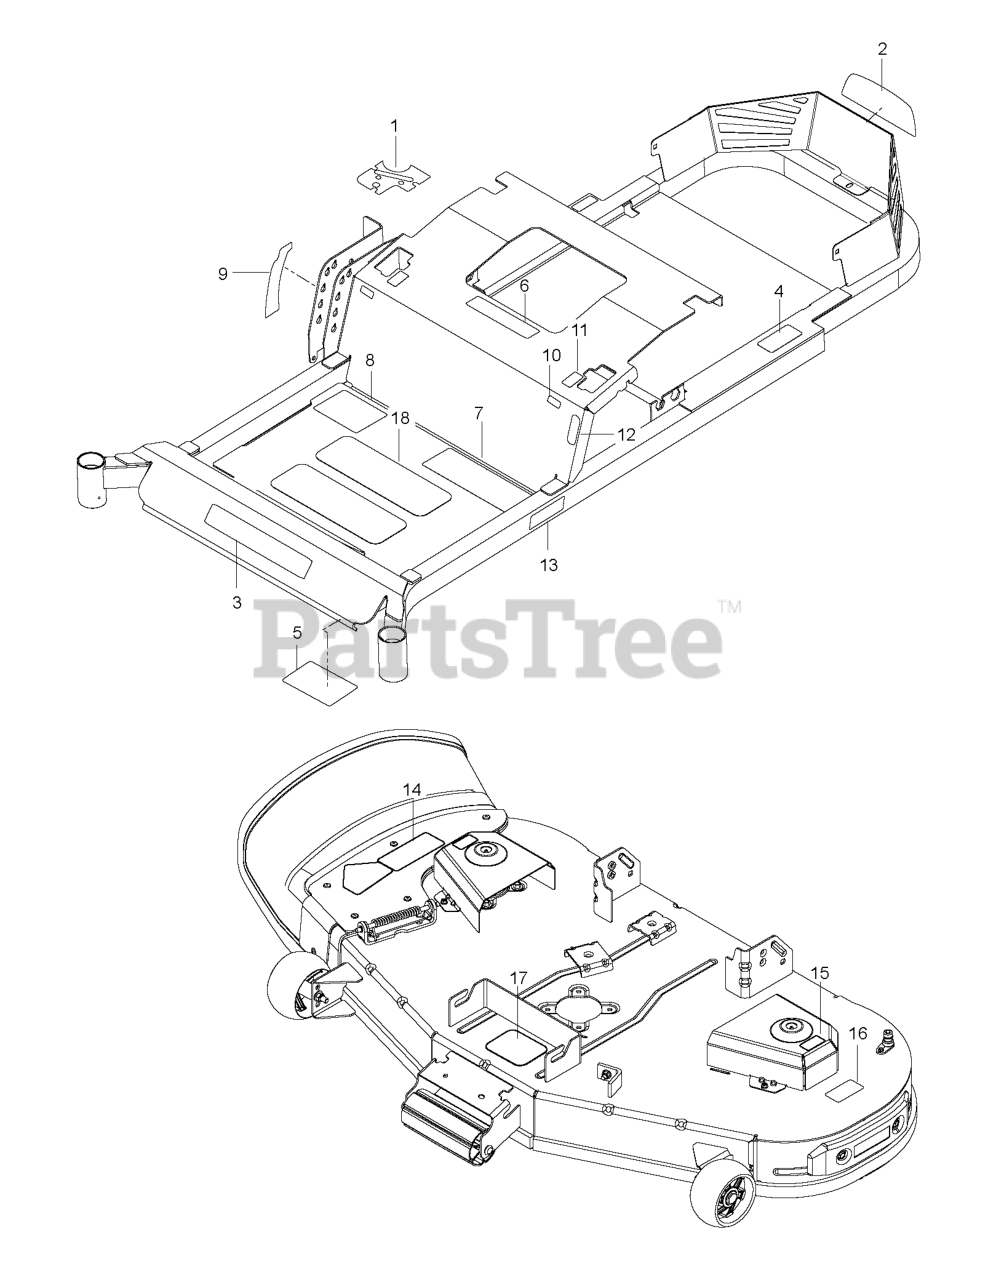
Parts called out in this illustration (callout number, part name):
1	DECAL CTRL PANEL GRAPHIC DECAL
2	DECAL ZTR BRAND GRAPHIC DECAL.
3	DECAL ZTR BRAND GRAPHIC DECAL.
4	DECAL, DO NOT TOW
5	DECAL, SERVICE
6	EURO DECAL-BATTERY WARNIN6
7	DECAL ZTR WARNING DECAL DECAL.
8	DECAL ZTR STARTING DECAL
9	DECAL.ZTR.HTADJ.LTRD.RZ2015PPR
10	DECAL.ZTR.TRACKING.GRAPHIC
11	DECAL.ZTR.MTNCONTROL.2015.PPRO
12	DECAL.ZTR.TRACKING.GRAPHIC
13	DECAL ZTR SIDE RAIL GRAPHIC DE
14	DECAL DECK WARNING GRAPHIC DEC
15	DECAL.DECK.CLEARCUT.NOSTEP
16	DECAL DECK DECAL DECAL.DECK.48
17	DECAL, BELT ROUTING
18	ANTI-SKID PAD
